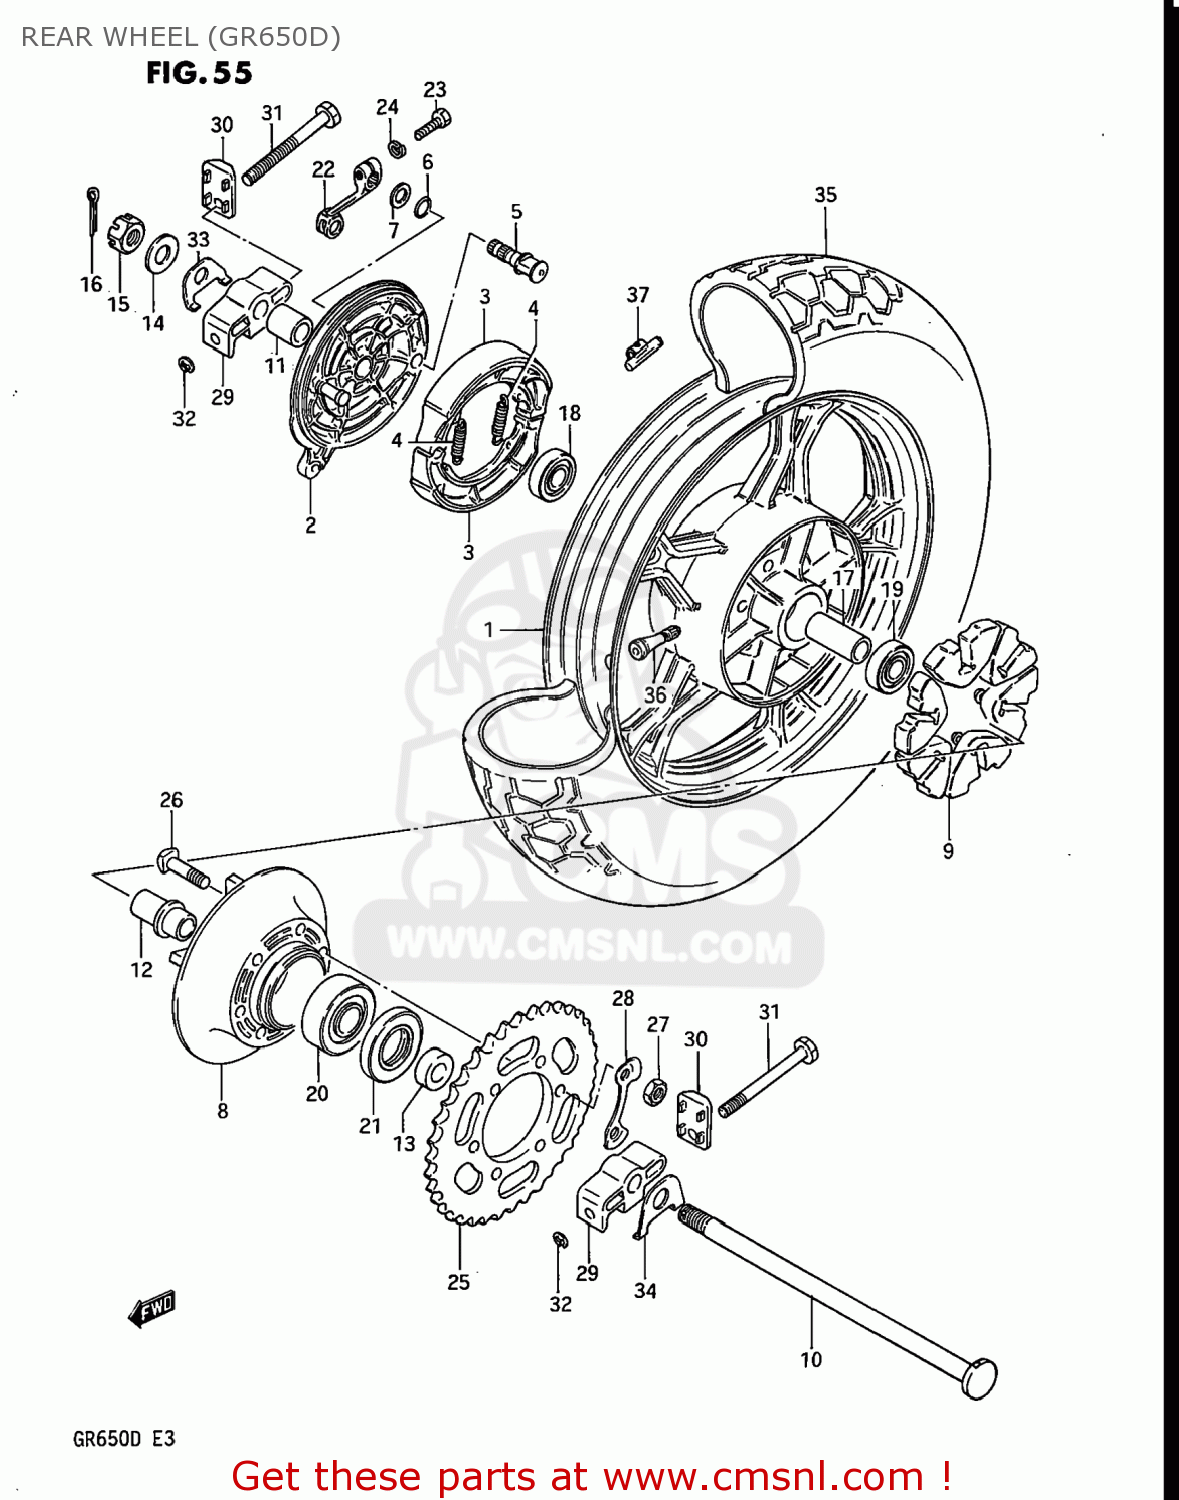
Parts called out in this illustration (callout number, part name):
1	WHEEL,REAR
2	PANEL,REAR HUB
3	SHOE,BRAKE
4	SPRING,BRAKE SHOE
5	CAM,FRONT BRAKE
6	O-RING,BOSS
7	WASHER (15X24X1.6)
8	DRUM,REAR SPROCKET MOUNT
9	ABSORBER,REAR HUB SHOCK
10	AXLE,REAR
11	SPACER (17.5X28X35)
12	RETAINER,RR SPROCKET DRUM
13	SPACER (17X33X12.5)
14	WASHER (17X30X3.2)
15	NUT
16	PIN,COTTER
17	SPACER(17.5X25X70)
18	BEARING
19	BEARING
20	BEARING
21	SEAL,OIL(33X62X7)
22	LEVER,REAR BRAKE CAM
23	BOLT
24	LOCK WASHER
25	SPROCKET,REAR
26	BOLT
27	NUT
28	WASHER
29	BODY,CHAIN ADJUSTER
30	PLATE,CHAIN ADJUSTER
31	BOLT,CHAIN ADJUSTER
32	E RING
33	WASHER,CHAIN ADJUSTER
34	WASHER,CHAIN ADJUSTER
35	TIRE
36	VALVE,TIRE
37	BALANCER,WHEEL
